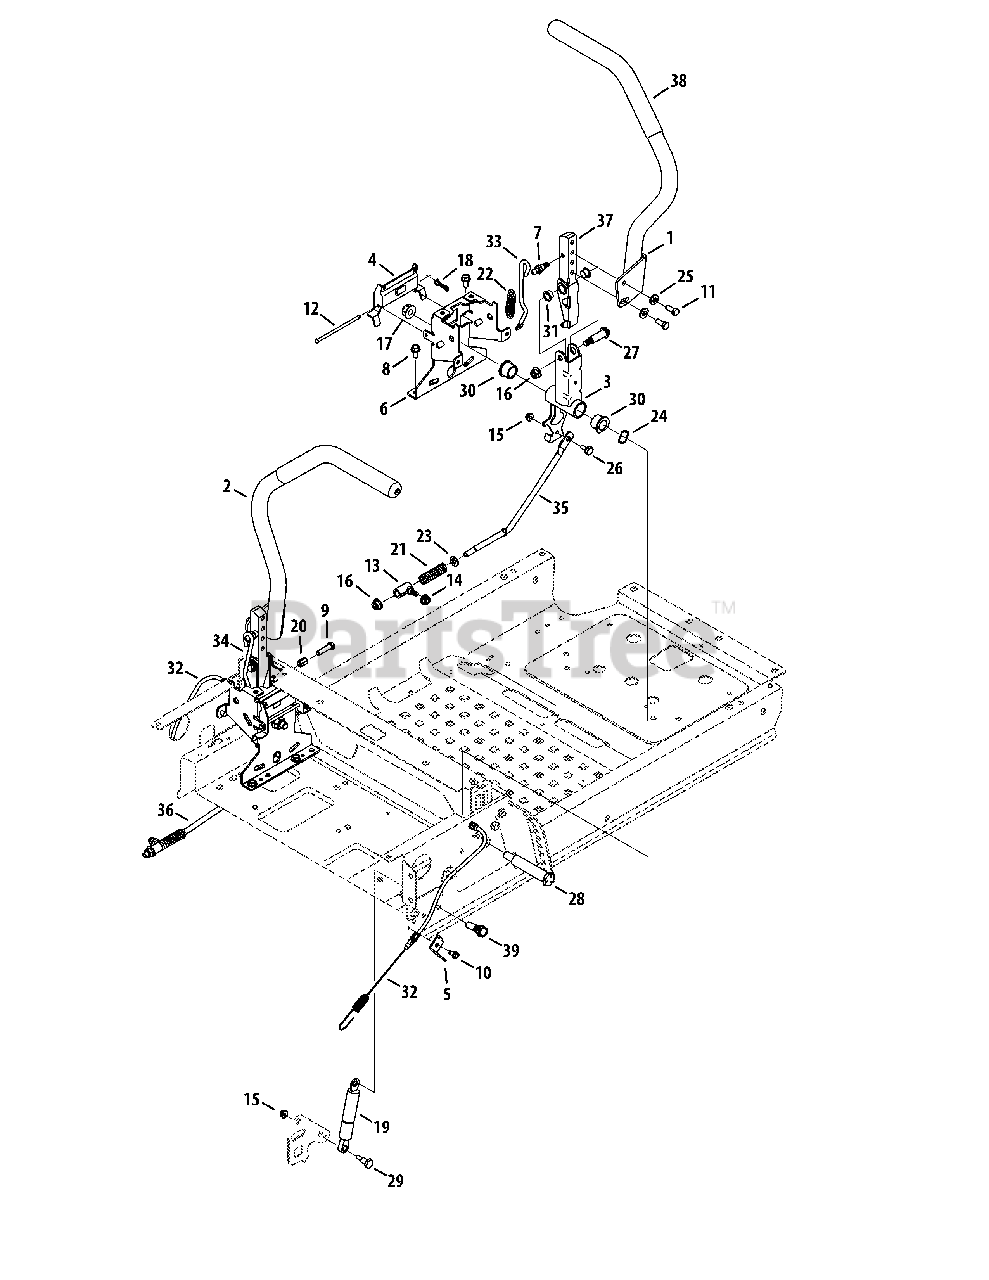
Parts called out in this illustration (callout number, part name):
1	RH Lapbar Lever Assembly
2	LH Labpar Lever Assembly
3	Lapbar Pivot Bracket
4	Brake Lever Actuator
5	Brake Cable Bracket
6	Lapbar Pivot Support Bracket
7	Shoulder Ball Screw 5/16-18 x .48
8	Hex Washer Screw 5/16-18 x .750
9	Hex Cap Screw 5/16-18 x 1.25
10	Hex Washer Screw 1/4-20 x .500
11	Hex Head Screw 5/16-18 x .75, Patch
12	Pin .188 x 4.1
13	Ferrule, 3/8 ID x .420 Shldr
14	Flange Lock Nut 5/16-18
15	Flange Lock Nut 1/4-20
16	Flange Lock Nut 3/8-16
17	Flange Lock Nut 1/2-13
18	Bow-Tie Cotter Pin
19	Dampener .87 OD x 7.06 Lg
20	Nut 5/16-18
21	Compression Spring .45 x 3.215
22	Extension Spring .56 x 2.31 x .105
23	Flat Washer .385 x .62 x .063
24	Washer, Wave .785 x 1.0 x .012
25	Flat Washer .344 x .750 x .120
26	Shoulder Screw .375 x .181
27	Shoulder Screw .498 Dia. x 1.296
28	Shoulder Screw .75 x 3.25 x 1/2-13
29	Shoulder Screw .395 Dia. x .56
30	Bearing .75 x 1.00 x .73
31	Flange Bearing .500 x .627
32	Parking Brake Cable
33	Lapbar Detent Rod, RH
34	Lapbar Detent Rod, LH
35	Hydro Control Rod, RH
36	Hydro Control Rod, LH
37	Lower Arm (w/bearing)
38	Lapbar Grip, Long 1.125 x 12.00 Lg
39	Shoulder Screw .395 Dia. x .83
